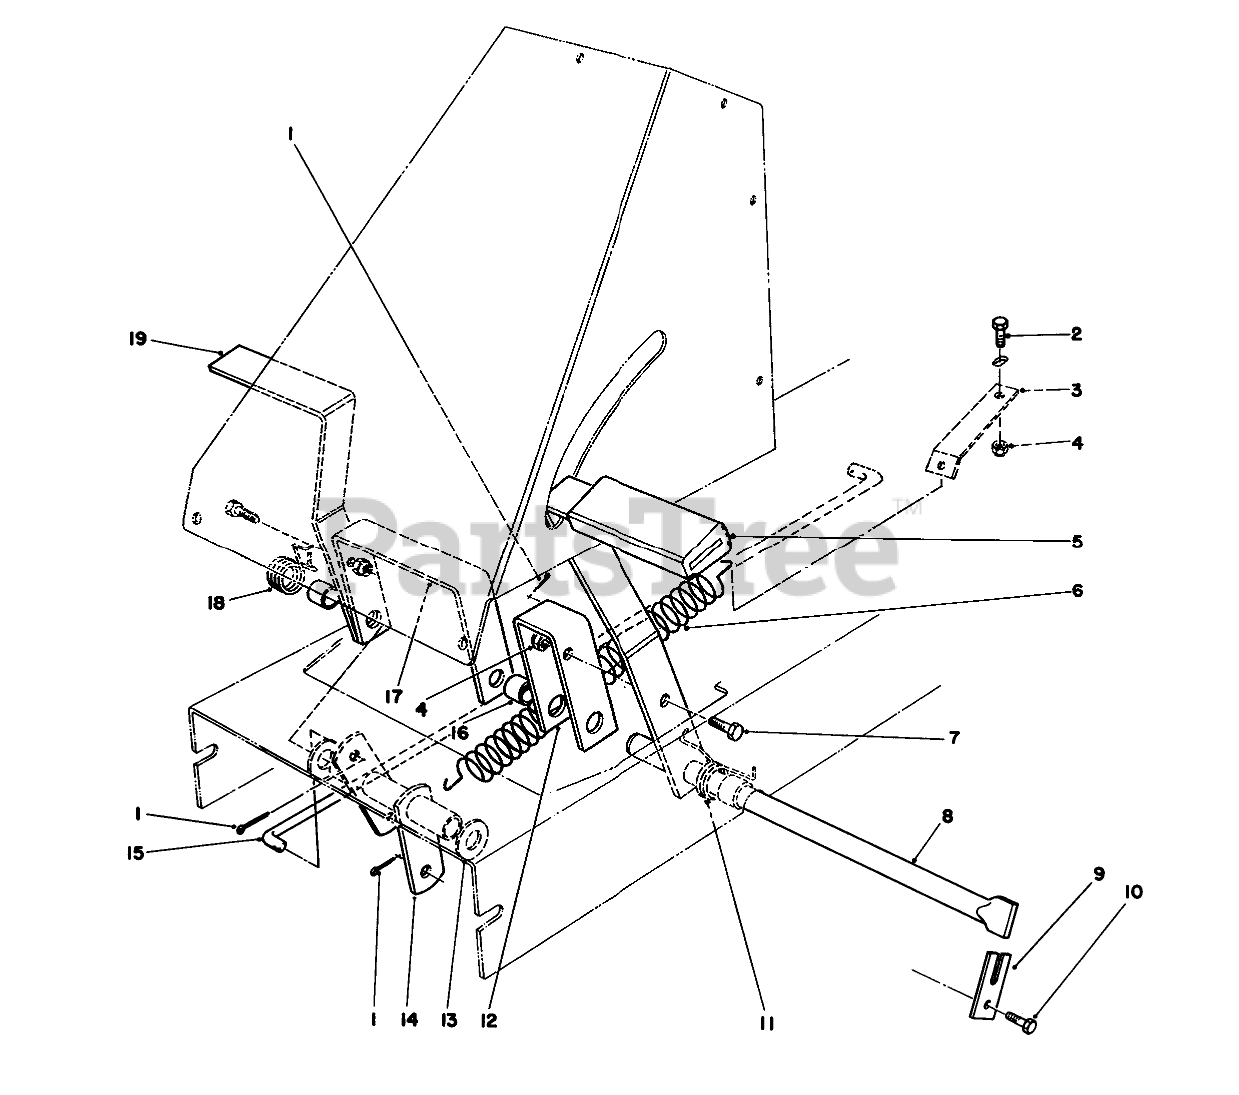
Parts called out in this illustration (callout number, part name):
1	PIN-COTTER
2	SCREW-HH
3	BRKT-SPRING RET
4	NUT-LOCK, NI
5	PAD-PEDAL
6	SPRING-EXTENSION
7	SCREW-HH
8	SHAFT-PEDAL PIVOT
9	RETAINER-SHAFT
10	SCREW-HH
11	SPRING-TORS CLUTCH
12	Bracket-Clutch Pedal
13	WASHER-FLAT
14	Pivot Tube
15	ROD-ENGAGE
16	SPACER-PEDAL
17	Bracket-Brake Pedal
18	SPRING-TORS BRAKE
19	Pedal
